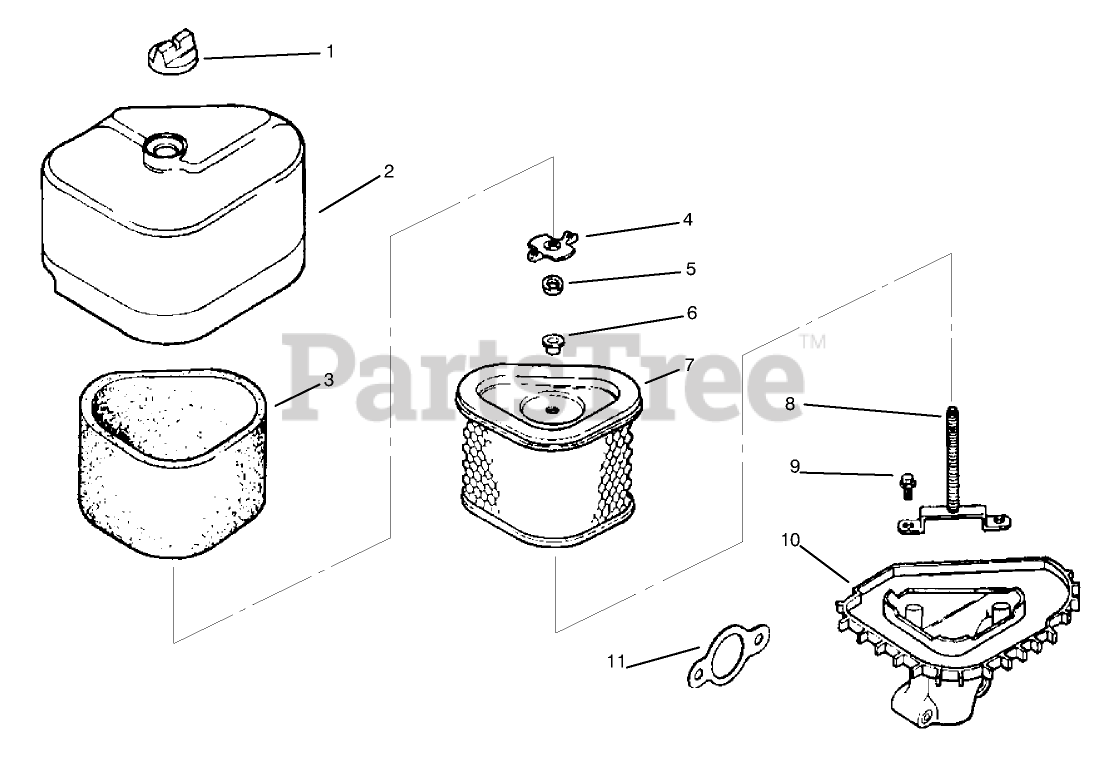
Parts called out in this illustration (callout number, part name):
1	Knob-Cover
2	Cover-Air Cleaner
3	Precleaner-Element
4	Wingnut
5	Washer
6	Grommet
7	Element-Air Cleaner
8	Stud-Mounting Plate
9	Screw
10	Base-Air Cleaner
11	Gasket-Air Cleaner
